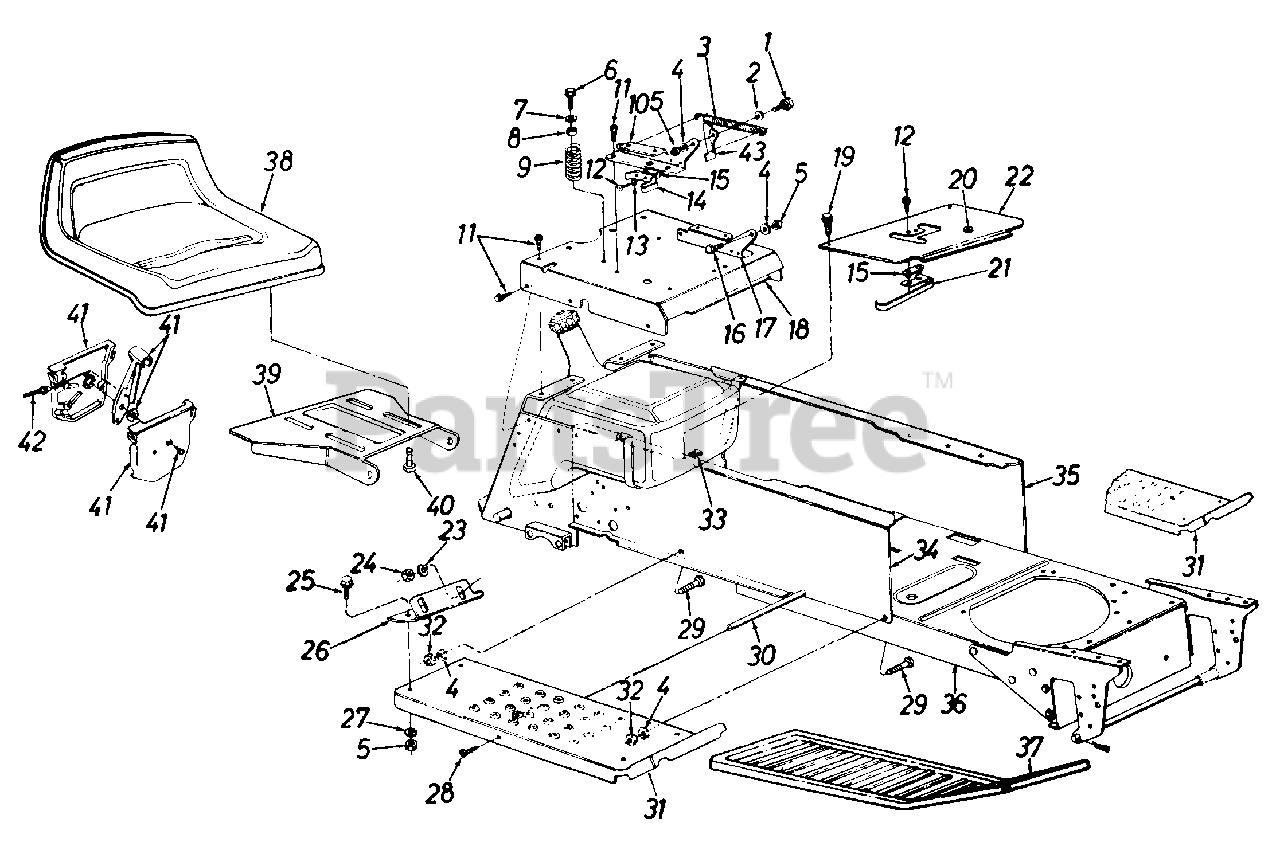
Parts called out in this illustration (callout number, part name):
1	Shld. Bolt .437" Dia. x .162"
2	Spr. Wash. .445" I.D.
3	Ext. Spring 5.31" Lg.
4	L-Wash. 5/16" I.D.
5	Hex Nut 5/16-18 Thd.
6	Hex Wash. Hd. Tap Scr. 5/16-18 x .7" Lg.
7	Fl-Wash..344" I.D.
8	Bushing
9	Compression Spring
10	Seat Pivot Brkt. Support-R.H.
11	Hex Wash. Hd. AB-Tap Scr. 5/16 x .75" Lg.
12	Hex Wash. Hd. AB-Tap Scr. #8 x .5" Lg.
13	Fiber Washer
14	Spring Switch
15	Insulator Nut Plate
16	Shld. Bolt .437" Dia. x .162"
17	Seat Pivot Brkt. Support-L.H.
18	Seat Plate
19	Truss Mach. B-Tap Scr. #10 x 5n Lg.
20	Snap Bushing
21	Reverse Safety Switch
22	Shift Cover
23	L-Wash. 1/4" I.D.
24	Hex Nut 1/4-20
25	Hex Bolt 5/16-18 x .75" Lg.
28	Truss Mach. Scr. 5/16-18 x .75" Lg.
29	Rib Neck Bolt 5/16-24 x .75" Lg.
30	Running Board Rod
33	Speed Nut #10Z
34	R.H. Side Frame
35	L.H. Side Frame
36	Lower Frame
37	Rubber Foot Pad
38	Seat Ass'y.
39	Seat Pivot Bracket
40	Hex Tap Scr. 3/8-16 x .75" Lg.
41	Throttle Control Box Ass'y.
42	Throttle Control Wire 35" Lg.
43	Seat Lift Bracket
